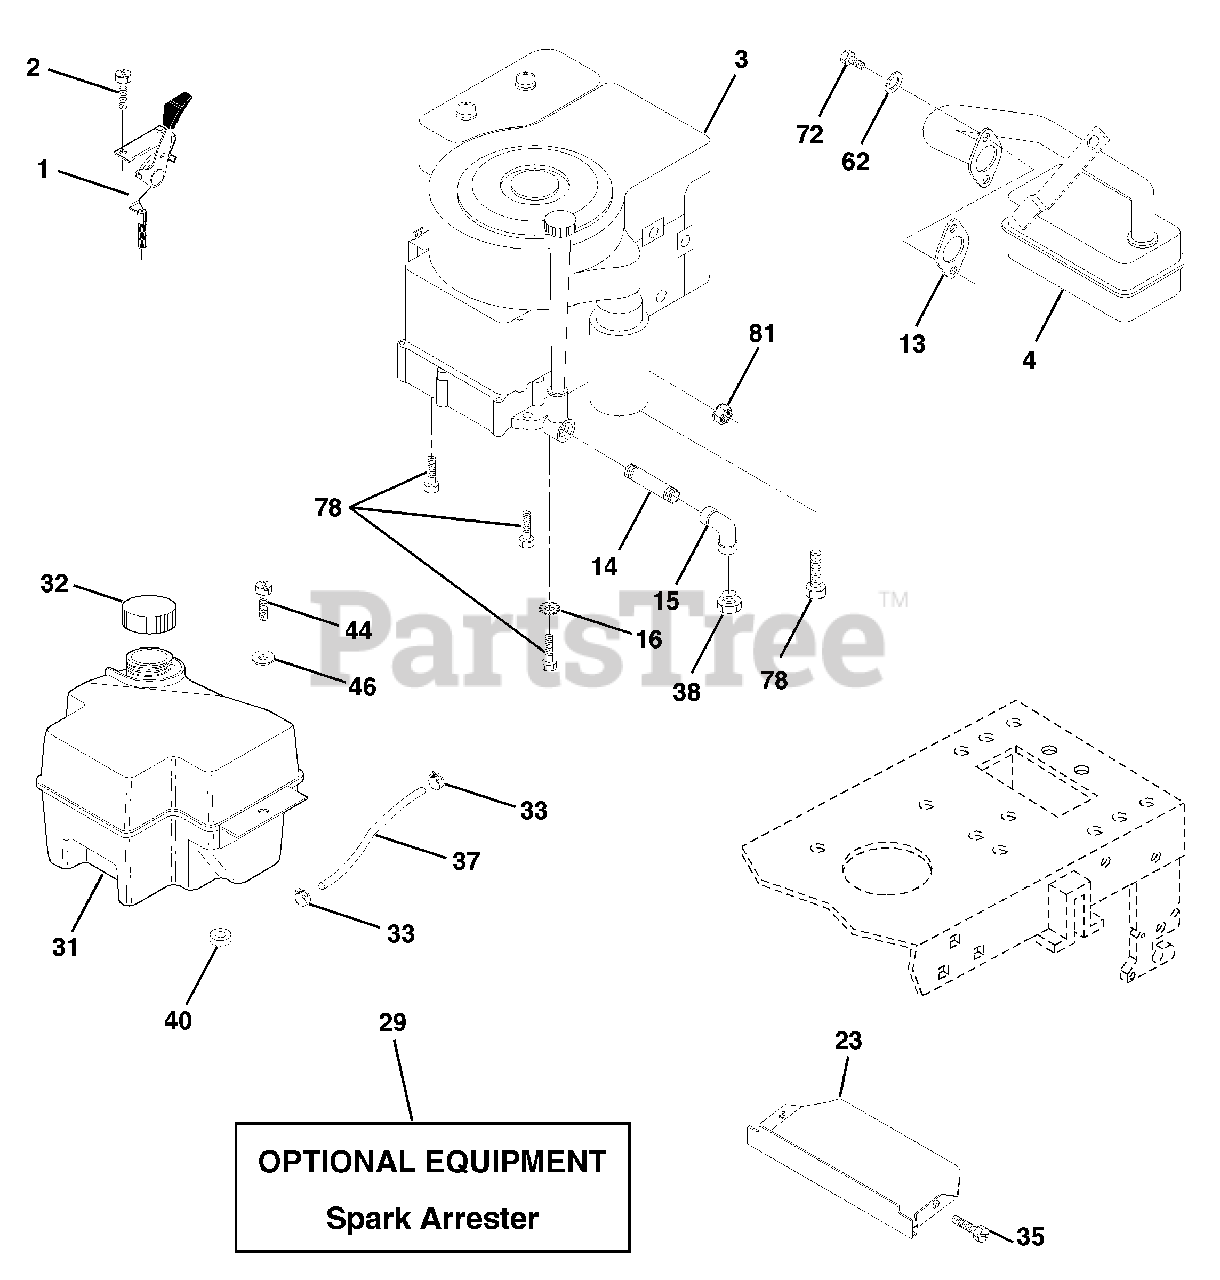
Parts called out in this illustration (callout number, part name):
1	Control Th/ch 23 5 LH Flag
2	Screw Hex Thd Cut 1/4-20x5/8 T
4	Muffler LT B&S 12/12.5/13HP
13	Gasket Eng
14	Nipple Pipe 3/8 Npt X 3"
15	Elbow Std 90 Degree 3/8-18 Npt
16	Washer Lock Ext Tooth 3/8
23	Shield Brn/Dbr Guard
29	Kit Spark Arrestor (Flat Scrn)
31	Tank Fuel Front 2 00
32	Cap Asm Fuel W/sym Vented
33	Clamp Hose Black
35	Screw
37	Line Fuel 20"
38	Plug Oil Drain
40	Bushing Snap Nyl Blk Fuel Line
44	Screw Hexwsh Thdrol 1/4-20x3/4
46	Washer 9/32 X 7/8 X 16 Ga
62	Washer Lock Hvy Hlcl Spr 5/16
72	Screw Hexhd Cap 5/16-18x 3/4
78	Screw Thdrol 3/8-16x1-1/4 TYTT
81	Nut Flange 1/4-20 Starter Nut
